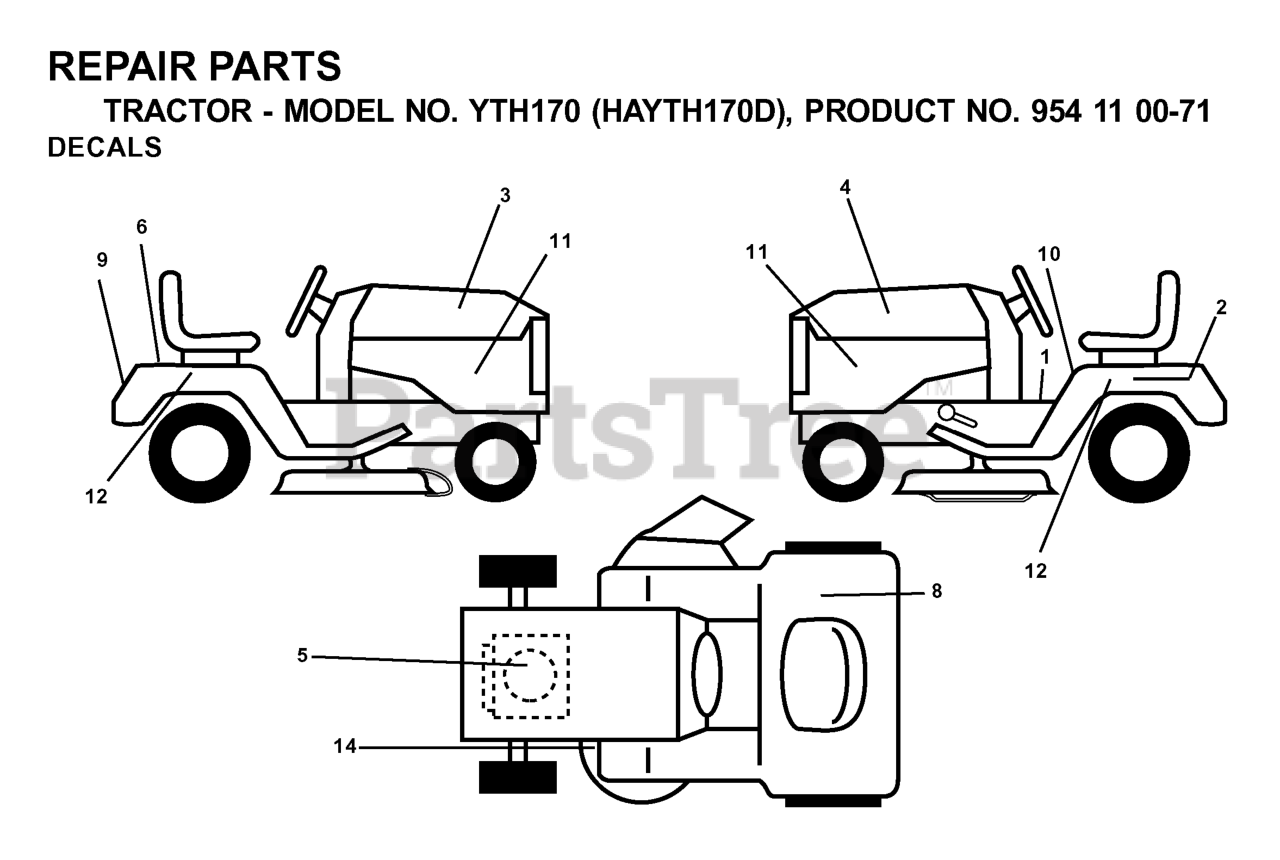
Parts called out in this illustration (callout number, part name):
2	DECAL BTRY SYMBOLS
6	DECAL
8	DECAL 80 DBA
9	DECAL FENDER HUSQ
11	DECAL PNL SIDE
14	DECAL V BELT SCHEMATIC
